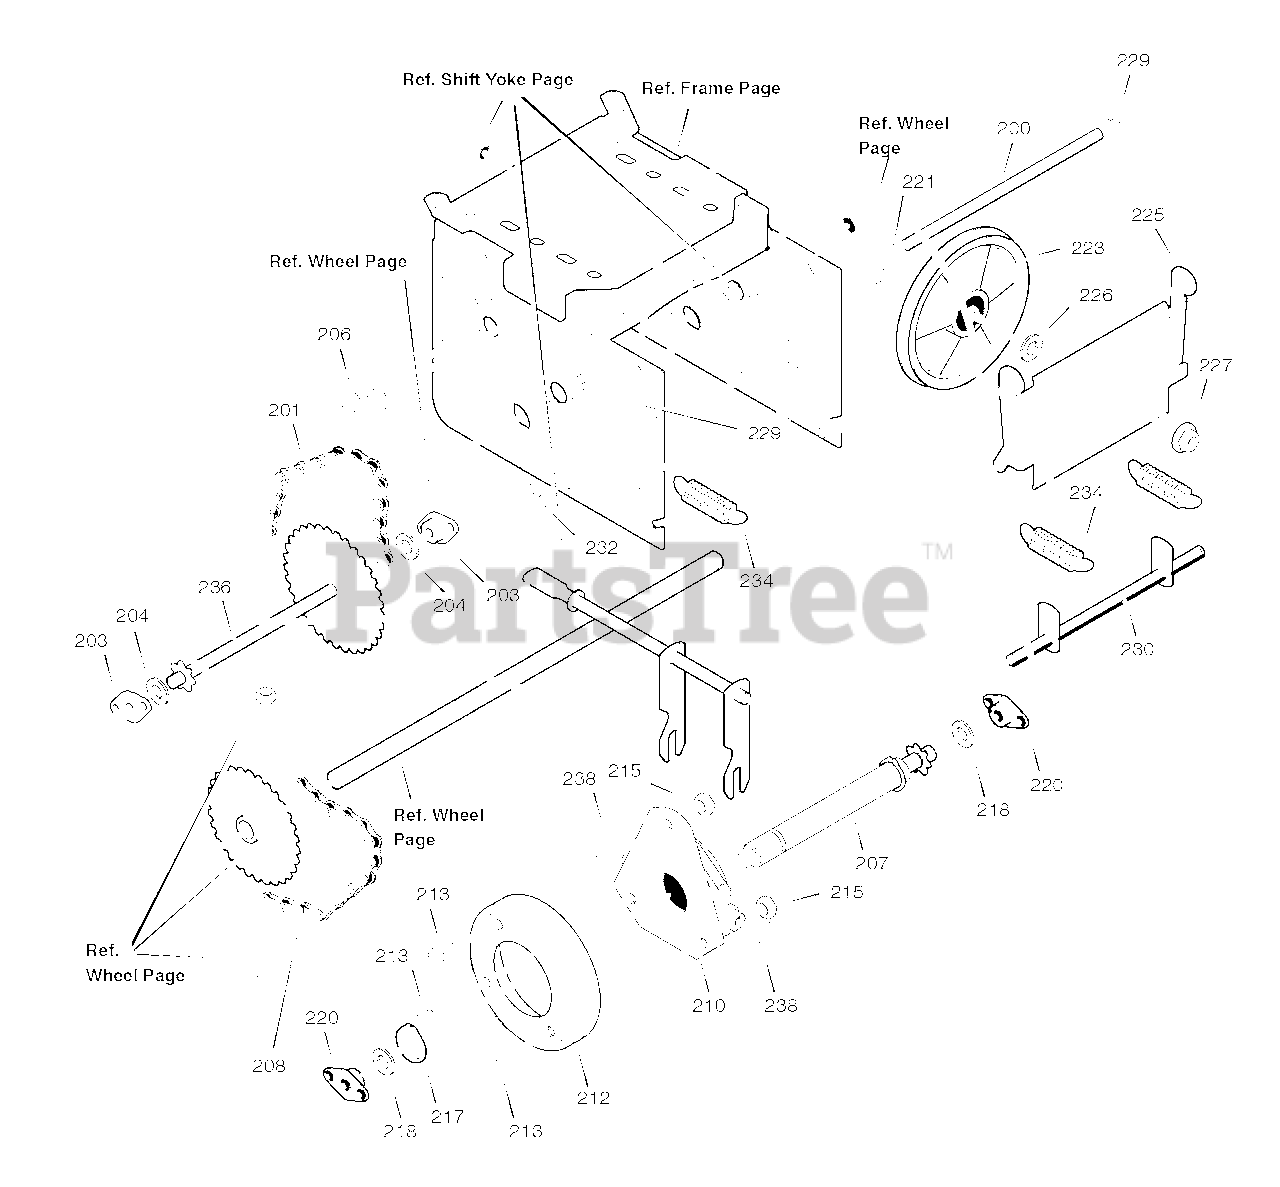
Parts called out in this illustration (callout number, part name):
200	LF AXLE, SWING PLATE YZ
201	CHAIN, ROLLER #420x19.00
203	BEARING AND RETAINER, ASSY
206	SCREW, TAP 5/16-18 x 0.5
207	ASSY, HEX SHAFT
208	CHAIN, ROLLER #420x18.00 LG
210	BEARING, TRUNION CLUTCH R
212	WHEEL, FRICTION DISC
215	NUT, KEPS HEX 1/4-20
217	RING, RETEXT
220	BEARING AND RETAINER, ASSY
221	SCREW, TAP 5/16-18 x .5
223	FRICTION PULLY
225	LF PLATE, SWINGING YZ
226	SPACER, FRICTION PULLEY
227	NUT, FLANGE LOCK 3/8-24
229	RETAINER, RING
230	LF ASSY, SPRING LINK YZ
232	RETAINER, RING
234	SPRING, EXTENSION
236	WLD, INTERMED SPROCKET 33T/7
238	WASHER, FLAT
